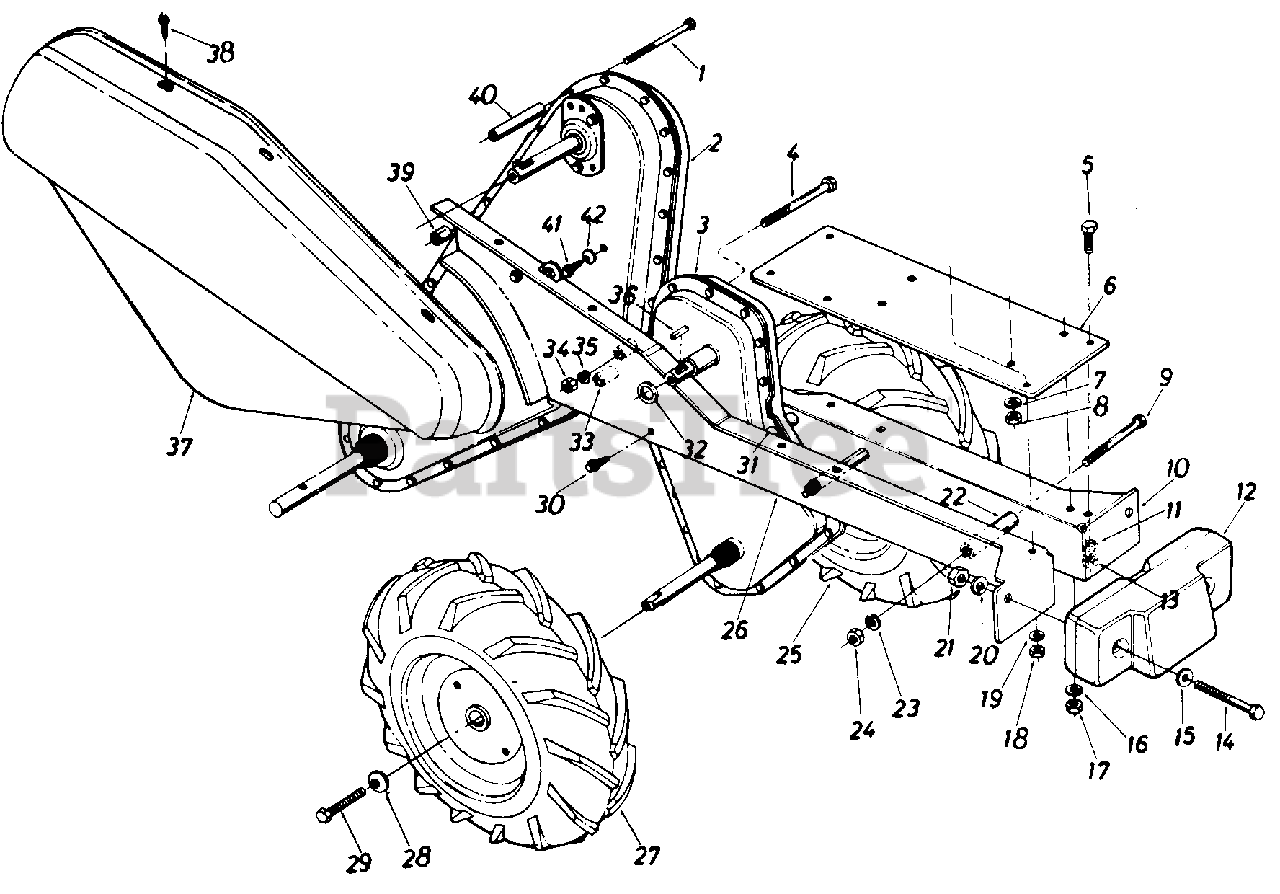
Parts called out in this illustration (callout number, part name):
1	Hex Bolt 5/16-18 x 3.00" Lg.*
2	Chai n Case Ass'y. Comp.-Tines
3	Chain Case Ass'y. Comp.-Wheels
4	Hex Bolt 5/16-18 x 3.00" Lg.*
5	Hex Bolt 5/16-18 x .75" Lg.*
8	Hex Nut 5/16-18 Thd.*
9	Hex Bolt 3/8-24 x 3.00" Lg.*
12	Weight 35#
13	Hex Nut 5/16-18 Thd.*
14	Hex Bolt 1/2-13 x 4.00" Lg.*
15	Fl-Wash. .510" I.D. x 1.0"O.D.
16	L-Wash. 5/16" I.D.*
17	Hex Nut 5/16-18 Thd.*
18	Hex Nut 5/16-18 Thd.*
19	L-Wash. 5/16" I.D.*
20	L-Wash. 1/2" I.D.*
21	Hex Nut 1/2-13 Thd.*
22	Spacer.38" I.D. x .62" O.D. x 2.18" Lg.
23	L-Wash. 3/8" I.D.*
24	Hex Nut 3/8-24 Thd.*
25	Wheel Ass'y. Comp. 12.5 x 3.5-L.H.
28	Belleville Wash. .345" I.D. x .88" O.D.
29	Hex Bolt 5/16-24 x .62" Lg.
30	Hex Wash. Hd. SF-Tap Scr. 5/16-24 x .50" Lg.
31	Spacer .326" I.D. x .47" O.D. x .96" Lg.
32	Fl-Wash. .635" I.D. x 1.00" O.D.
33	Spacer.326" I.D. x .47" O.D. x .96" Lg.
34	Hex Nut 5/16-18 Thd.
35	L-Wash. 5/16" I.D.
36	Sq. Key 3/16 x .75" Lg.
37	Belt Cover
38	Hex Wash. Hd. SF-Tap Scr. 1/4-20 x .50" Lg.
39	Spacer.326" I.D. x .47" O.D. x .96" Lg.
40	Spacer.375" I.D. x .500" O.D. x 2.00" Lg.
41	Hex Wash. Hd. SF-Tap Scr. 1/4-20 x .50" Lg.
42	Bell-Wash. .265" I.D. x .75" O.D.
